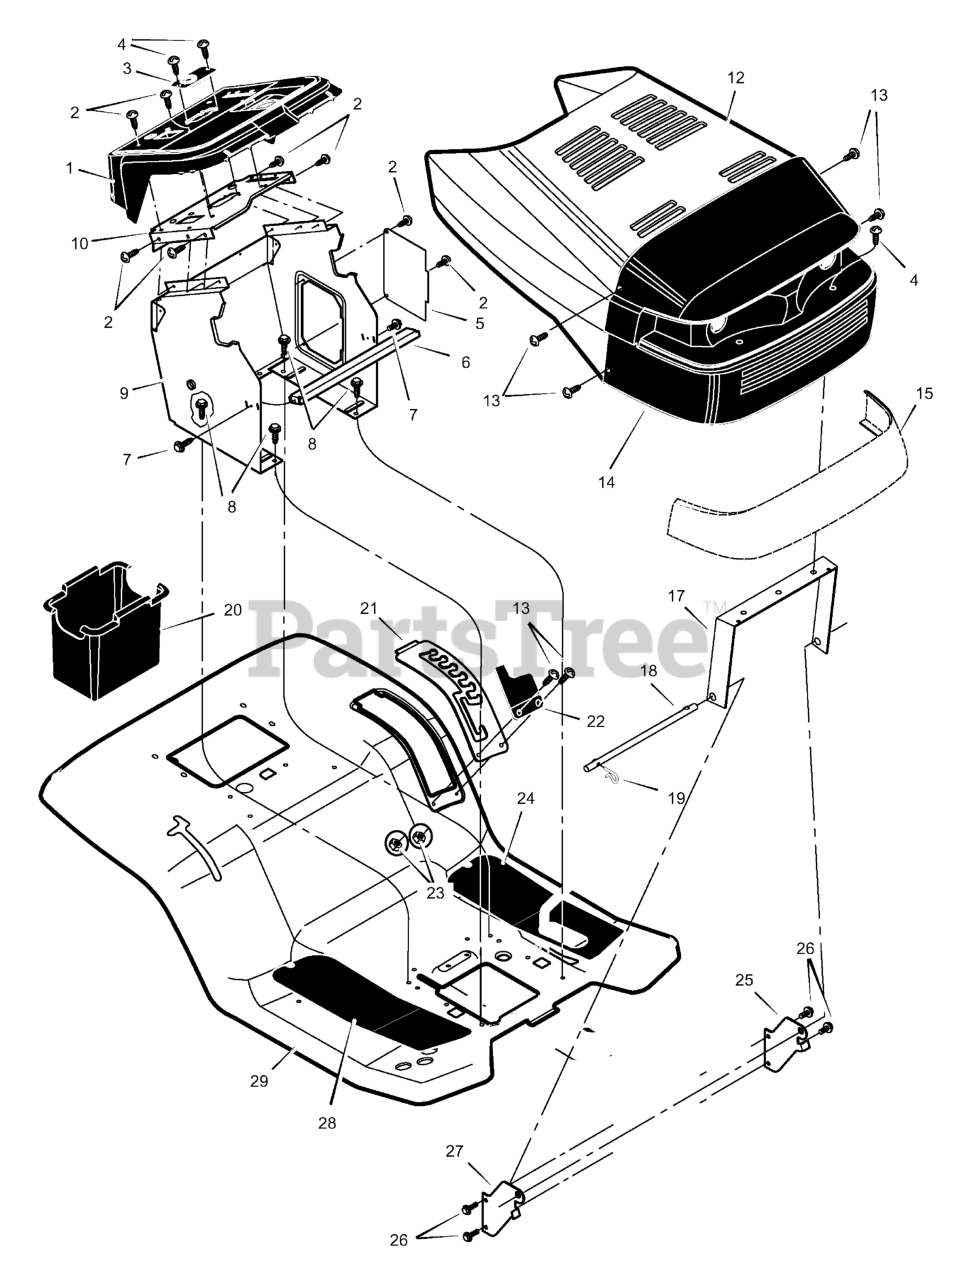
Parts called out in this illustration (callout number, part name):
2	Screw
3	Bearing, Upper Steering
5	Panel, Side Access
6	Channel, Support
9	Support, Dash
10	Plate, Dash
13	Bolt, Shoulder
14	Grille
17	Brace, Grille
18	Rod, Pivot
19	Pin, Hair
20	Container, Battery
21	Plate, Lift Detent
24	Mat, Left
25	Support, Left Grille
27	Support, Right Grille
28	Mat, Right
29	Deck, Seat
30	Decal, Left Hood
